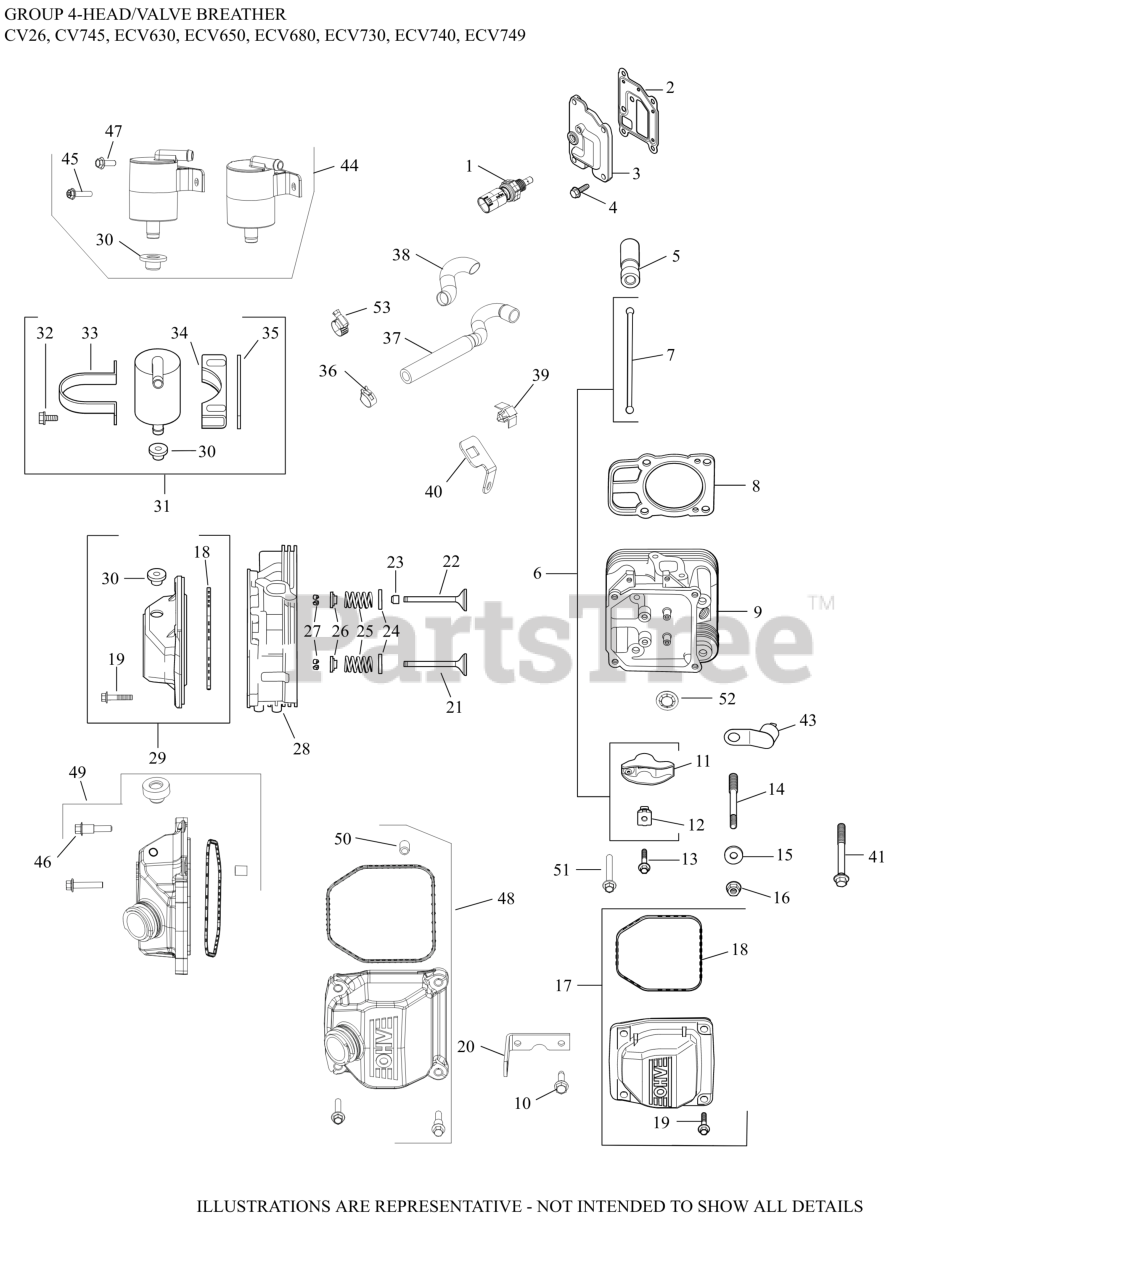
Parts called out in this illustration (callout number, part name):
2	GASKET, BREATHER
3	KIT, BREATHER COVER W/GASKET
4	SCREW, THREAD FORMING
5	LIFTER, VALVE HYDRAULIC-USE 25 351 11-S
6	KIT, VALVE TRAIN
7	ROD, PUSH
8	KIT, GASKET CYLINDER HEAD
9	HEAD, ASSY CYL (#2)-(#24318201S)
10	SCREW, THREAD FORMING
11	ARM, ROCKER
12	PIVOT, ROCKER ARM
13	SCREW, FLG (BLACK) M6X1.0X34
14	STUD, M8X1.25
15	WASHER, FLAT 8.6 MM
16	NUT, FLG M8X1.25
17	KIT, VALVE COVER-PLAIN (PLASTIC)
18	O-RING (YELLOW), VALVE CO
19	SCREW, FLG M6X1.0X30
20	STRAP, LIFT
21	VALVE, EXHAUST
21	VALVE, EXHAUST (.25)
22	VALVE, INTAKE (STD)
22	VALVE, INTAKE (.25)
23	SEAL, VALVE BAND
24	RETAINER, SPRING
25	SPRING, VALVE
26	KIT, RETAINER
27	CAP, VALVE SPRING
28	HEAD, ASSY CYL (#1)-(#24318200S)
29	KIT, VALVE COVER
30	GROMMET, RUBBER
36	CLAMP, HOSE (KM)-USE 25 237 31-S
37	HOSE, FLEXIBLE
44	KIT, BREATHER SEPARATOR
47	SCREW, HI-LOW
52	RETAINER, VALVE GUIDE (KM)
